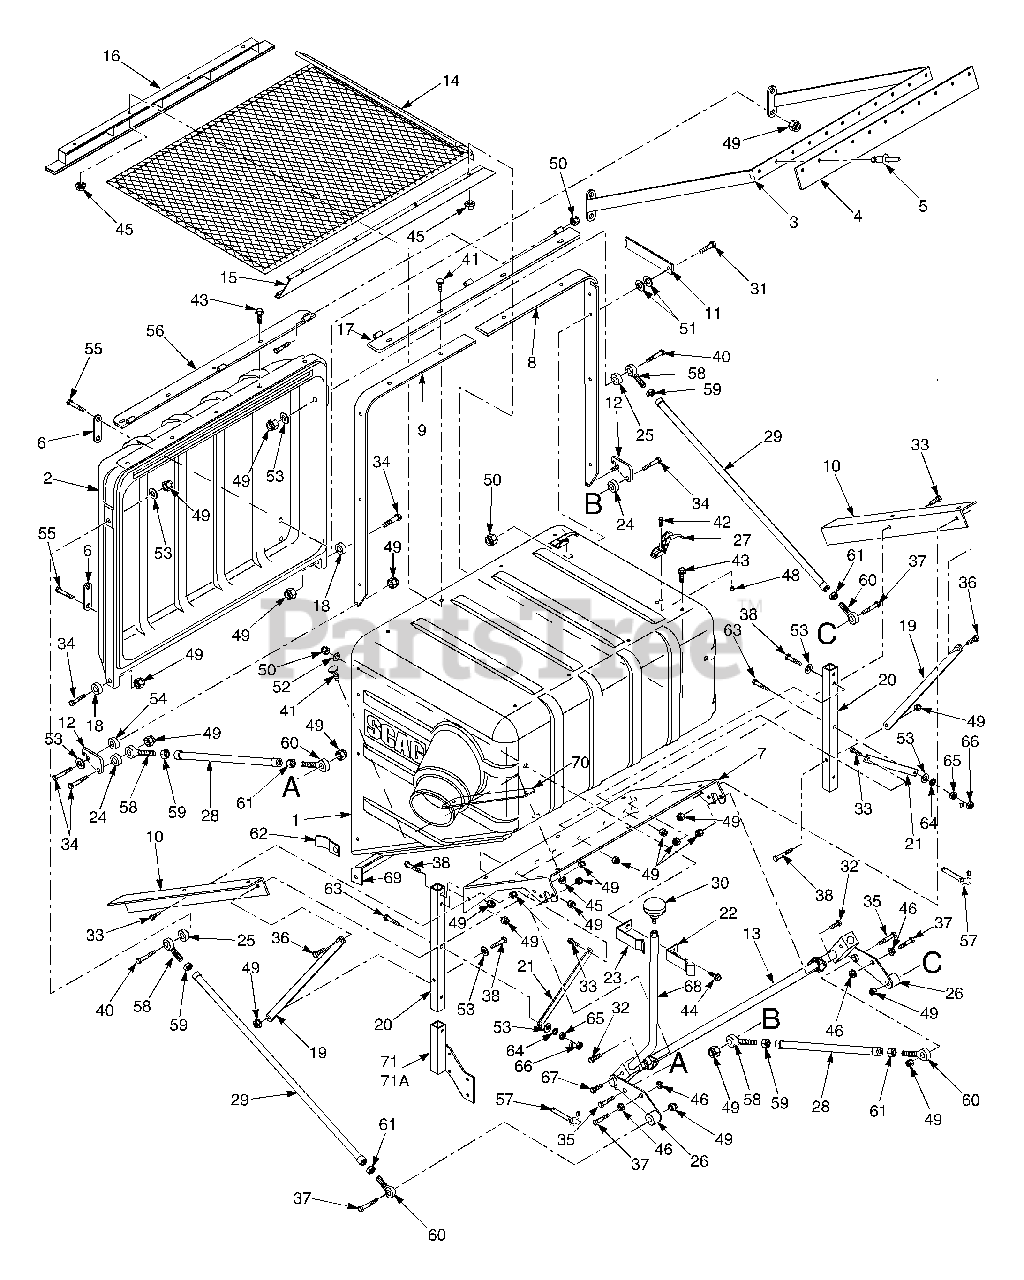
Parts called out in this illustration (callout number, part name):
1	Hopper, GC-STC-CS
2	Door, GC-CS
3	Sweeper Weldment, GC-CS
4	Pad, Rubber
5	Pop Rivet, 3/16 x .652
6	Plate, Stiffener
7	Support Frame, Hopper
8	Hinge Bracket, L.H.
9	Hinge Bracket, R.H.
10	Bracket, Hopper Support
11	Latch, Door Prop
12	Plate, Latch
13	Bellcrank Weldment, Upper
14	Debris Screen Weldment
15	Screen Support Weldment, Rear
16	Screen Support Weldment, Front
17	Hinge Weldment, Hopper
18	Spacer
19	Brace Stiffener, Short
20	Tube, Upright
21	Brace, Engine Mount
22	Latch, Dump Rod Inner
23	Latch, Dump Rod Outer
24	Spacer
25	Spacer
26	Spacer
27	Latch, Hood
28	Linkage Assembly, Lower
29	Linkage Assembly, Upper
31	Bolt, Hex Head 5/16-18 x 1-1/4
32	Bolt, Hex Head 3/8-16 x 3/4"
33	Bolt, Hex Head 3/8-16 x 1"
34	Bolt, Hex Head 3/8-16 x 1-1/2"
35	Bolt, Hex Head 3/8-16 x 1-3/4"
36	Bolt, Hex Head 3/8-16 x 1-1/4"
37	Bolt, Hex Head 3/8-16 x 2"
38	Bolt, Hex Head 3/8-16 x 2-1/4"
39	Bolt, Hex Head 5/16-18 x 3-1/2"
40	Bolt, Hex Head 3/8-16 x 3-1/2"
41	Bolt, Carriage 5/16-18 x 1"
42	Screw, #10-32 x 1/2"
43	Cap Screw, 5/16-18 x 3/4" Serr. Flan.
44	Cap Screw, 5/16-18 x 1" Serr. Flan.
45	Nut, 5/16-18 Serrated Flange
46	Nut, 3/8-16 Serrated Flange
47	Nut, 3/8-16 UNC Jam
48	Nut, #10-32 Elastic Stop
49	Nut, 3/8-16 Elastic Stop
50	Nut, 5/16-18 Elastic Stop
51	Washer, Special Wave
52	Washer, 5/16-.375 x .875 x .083 Flat
53	Washer, 3/8-.931 x .938 x .105 Flat
54	Bushing, Hopper Latch GC-CS
55	Bolt, Hex Head 3/8-16 x 3"
56	Hinge Weldment, Door
57	Lanyard
58	Rod End Male, 3/8-24 L.H. Thread
59	Nut, 3/8-24 UNF L.H. Thread
60	Rod End Male, 3/8-24 R.H. Thread
61	Nut, 3/8-24 UNF R.H. Thread
62	Alignment Bracket, GC-CS
63	Bolt, Hex Head 3/8-16 x 2-1/2"
64	Lock Wasker, 3/8-16 Spring
65	Nut, 3/8-16 UNC Zinc
66	Nut, 3/8-16 Center Lock
67	Bolt, Hex Head 5/16-18 1-3/4"
68	Rod, Dump Lever
69	Bracket, Lower Stiffener
70	Retainer Strip, Hopper
71	Mounting Bracket Weldment, R.H.
71A	Mounting Bracket Weldment, L.H.
